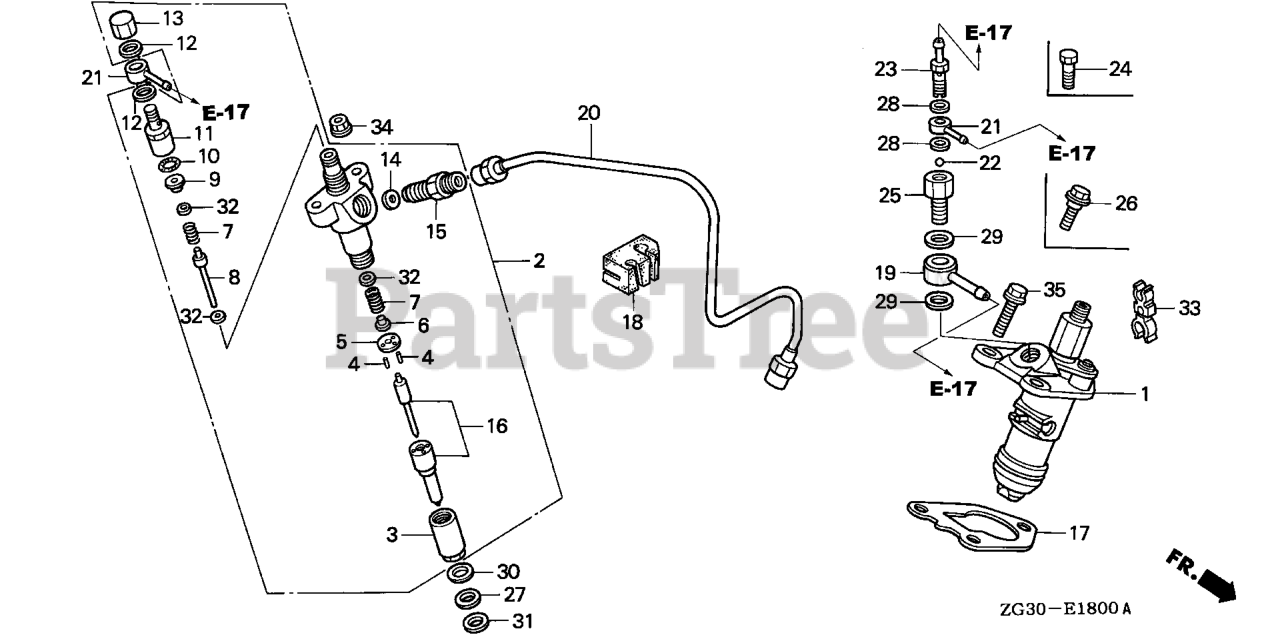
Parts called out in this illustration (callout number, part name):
1	PUMP ASSY., FUEL INJECTION
2	NOZZLE & HOLDER ASSY.
3	NUT, RETAINING
4	PIN (1.78X9.3)
5	SPACER
6	SEAT, SPRING (A)
7	SPRING, NOZZLE
8	ROD, PUSH
9	SEAT, SPRING (B)
10	O-RING
11	NUT, CAP
12	GASKET A
13	NUT
14	GASKET B
15	CONNECTOR, IN.
16	NOZZLE
17	GASKET, FUEL INJECTION PUMP (0.2) (C)
17	GASKET, FUEL INJECTION PUMP (0.3) (D)
17	GASKET, FUEL INJECTION PUMP (0.4) (E)
17	GASKET, FUEL INJECTION PUMP (0.1) (A)
17	GASKET, FUEL INJECTION PUMP (0.15) (B)
17	GASKET, FUEL INJECTION PUMP (0.5) (F)
17	GASKET, FUEL INJECTION PUMP (0.6) (G)
18	RUBBER, FUEL TUBE CLAMP
19	JOINT, FUEL
20	PIPE, FUEL
21	JOINT, AIR BREATHER (B)
22	BALL, CHECK
23	BOLT, AIR BREATHER (8X20)
25	BOLT, FUEL JOINT (12X25.5)
26	BOLT, ROTARY TRANSMISSION
27	WASHER, PLAIN (7MM)
28	WASHER (8MM)
29	WASHER, FUEL JOINT
30	GASKET A, NOZZLE (0.8) Use from Engine SN 1006485.
30	GASKET B, NOZZLE (1.0) Use from Engine SN 1012019.
30	GASKET, NOZZLE
30	GASKET D, NOZZLE (1.4) Use from Engine SN 1006485.
31	GASKET, SPECIAL (7MM)
32	SHIM A (0.50)
32	SHIM B (0.51)
32	SHIM C (0.52)
32	SHIM D (0.53)
32	SHIM E (0.54)
32	SHIM F (0.55)
32	SHIM G (0.56)
32	SHIM H (0.57)
32	SHIM I (0.58)
32	SHIM J (0.59)
32	SHIM K (0.60)
32	SHIM L (0.70)
32	SHIM M (0.80)
32	SHIM N (0.90)
34	NUT, FLANGE (6MM)
35	BOLT, FLANGE (8X25)
